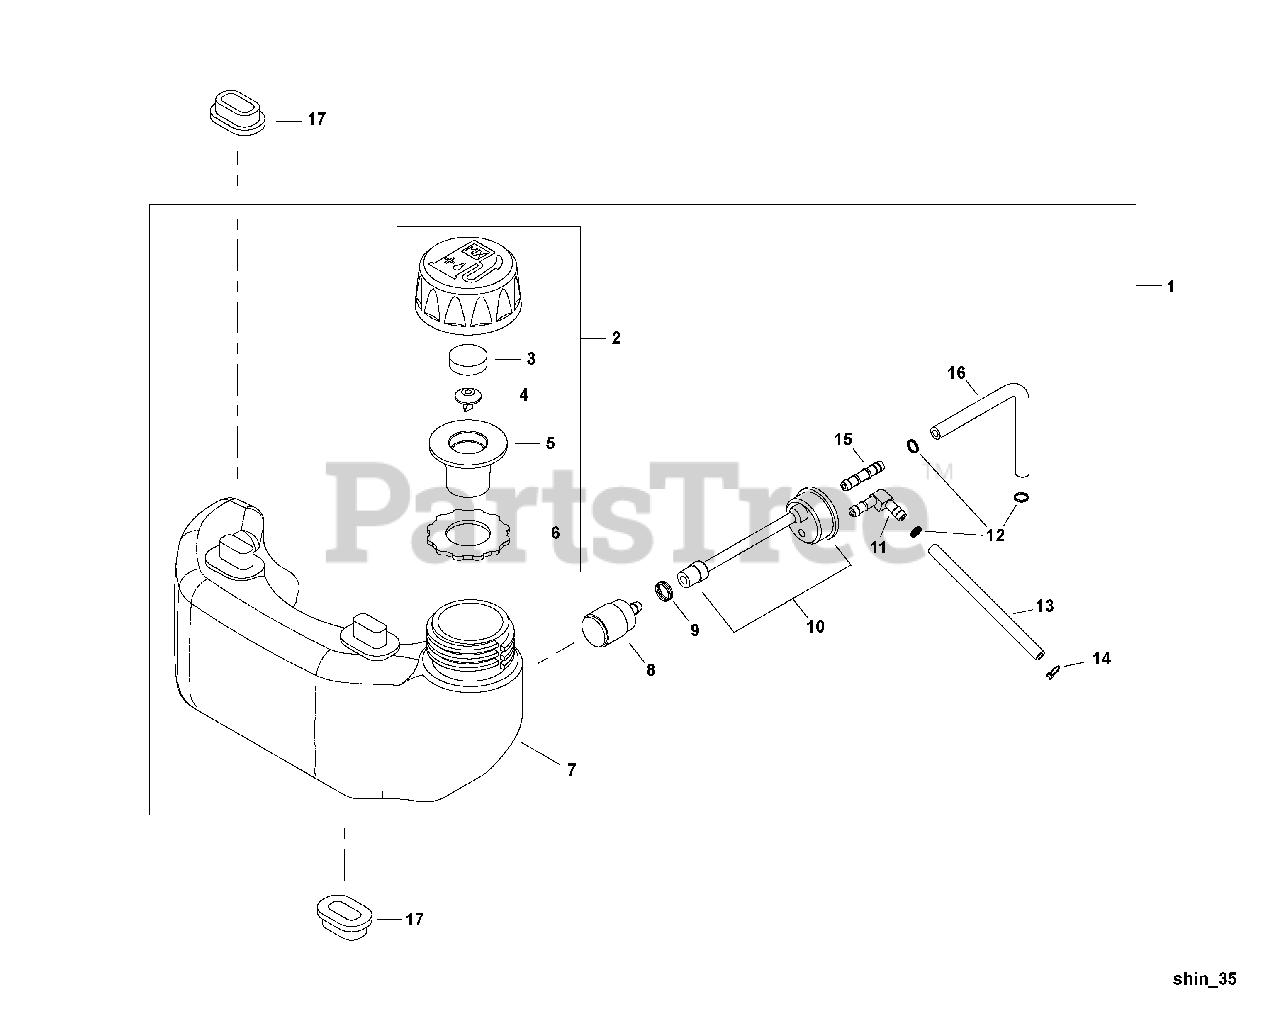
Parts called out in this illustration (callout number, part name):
1	FUEL TANK ASSY
2	CAP ASSY
4	VENT, FUEL TANK
5	HOLDER, VENT
6	GASKET, CAP
7	TANK, FUEL
8	FILTER, FUEL
9	CLIP - 7.8
10	FUEL PIPE ASSY
11	CONNECTOR, PIPE
12	CLIP - 6
13	PIPE - CLEAR
14	CLIP - BUTTERFLY
15	CONNECTOR, PIPE
16	PIPE - FUEL
17	CUSHION, FUEL TANK
